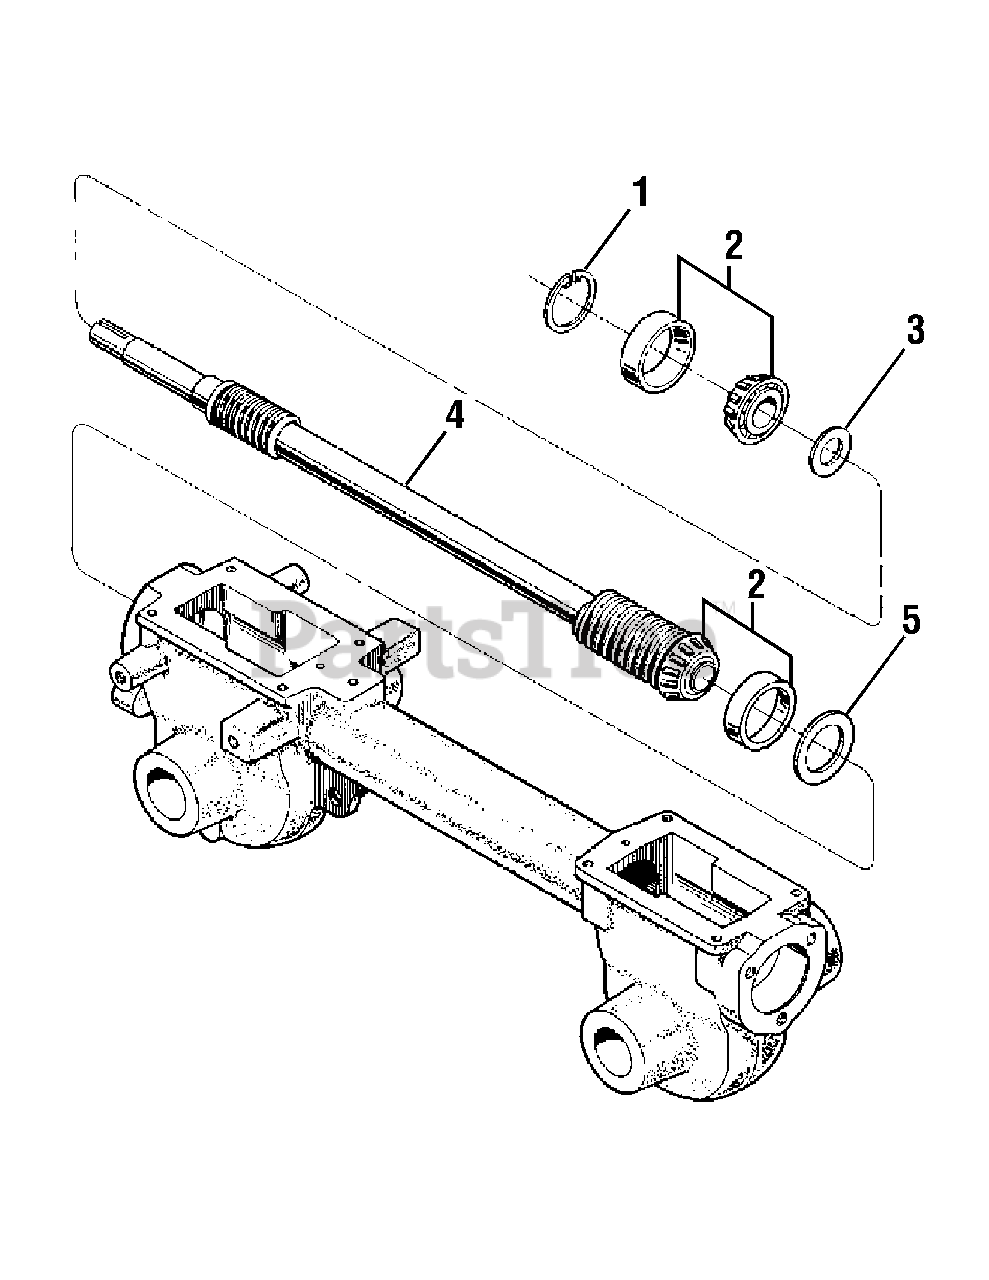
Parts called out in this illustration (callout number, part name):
1	Snap Ring
2	Bearing, Tapered Roller (with race)
3	Support Washer, Rear
4	Drive Shaft
5	Shim, Rear Bearing Cap, .010" thick
5	Shim, same as above, except .030" thick
5	Shim, same as above, except .005" thick
5	Shim, same as above, except .062" thick
